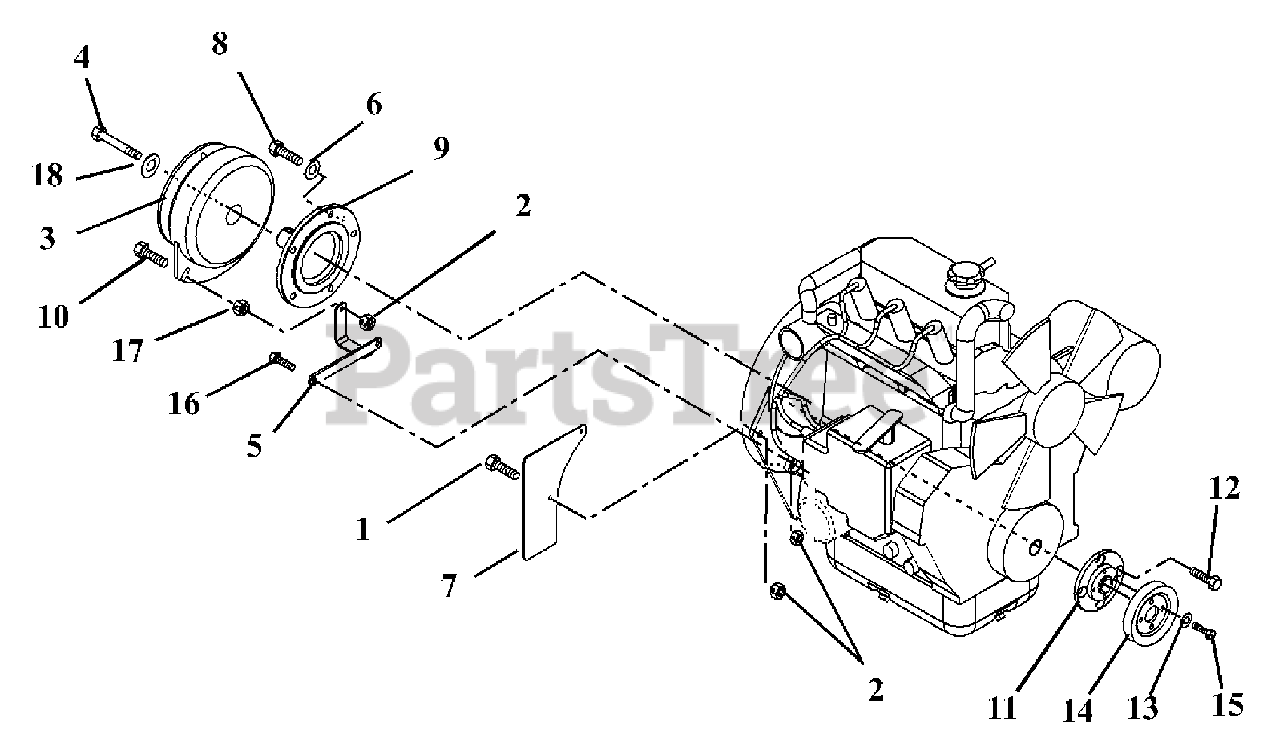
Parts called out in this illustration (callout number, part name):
1	@BLT-HEX .31-18X.75 GR5 YWZC
2	@NUT-LK-TOP-FLG .31-18 YWZC
3	CLUTCH, WARNER 6.323 O/PIN
4	BLT-HEX .44-20X2.50 GR5 YWZC
5	STABILIZER, CLUTCH
6	@WSHR-LK .31X.078 REG YWZC
7	GUARD, FLYWHEEL
8	BLT, HEX M8-1.25X25 GR8.8YWZC
9	SHAFT, STUB (BRIGGS-DIESEL)
10	@BLT-HEX .31-18X1.50 GR5 YWZC
11	ADAPTER, SHEAVE (DIESEL)
12	BLT, FSCHS M8-1.25X25
13	@WSHR-LK .25X.062 REG YWZC
14	SHEAVE, POLY V 1.000 X 3.25
15	@BLT-HEX .25-20X.75 GR5 YWZC
16	@BLT-HEX .31-18X1.00 GR5 YWZC
17	@NUT-HEX .31-18 YWZC
18	@WSHR-LK .44X.109 REG YWZC
